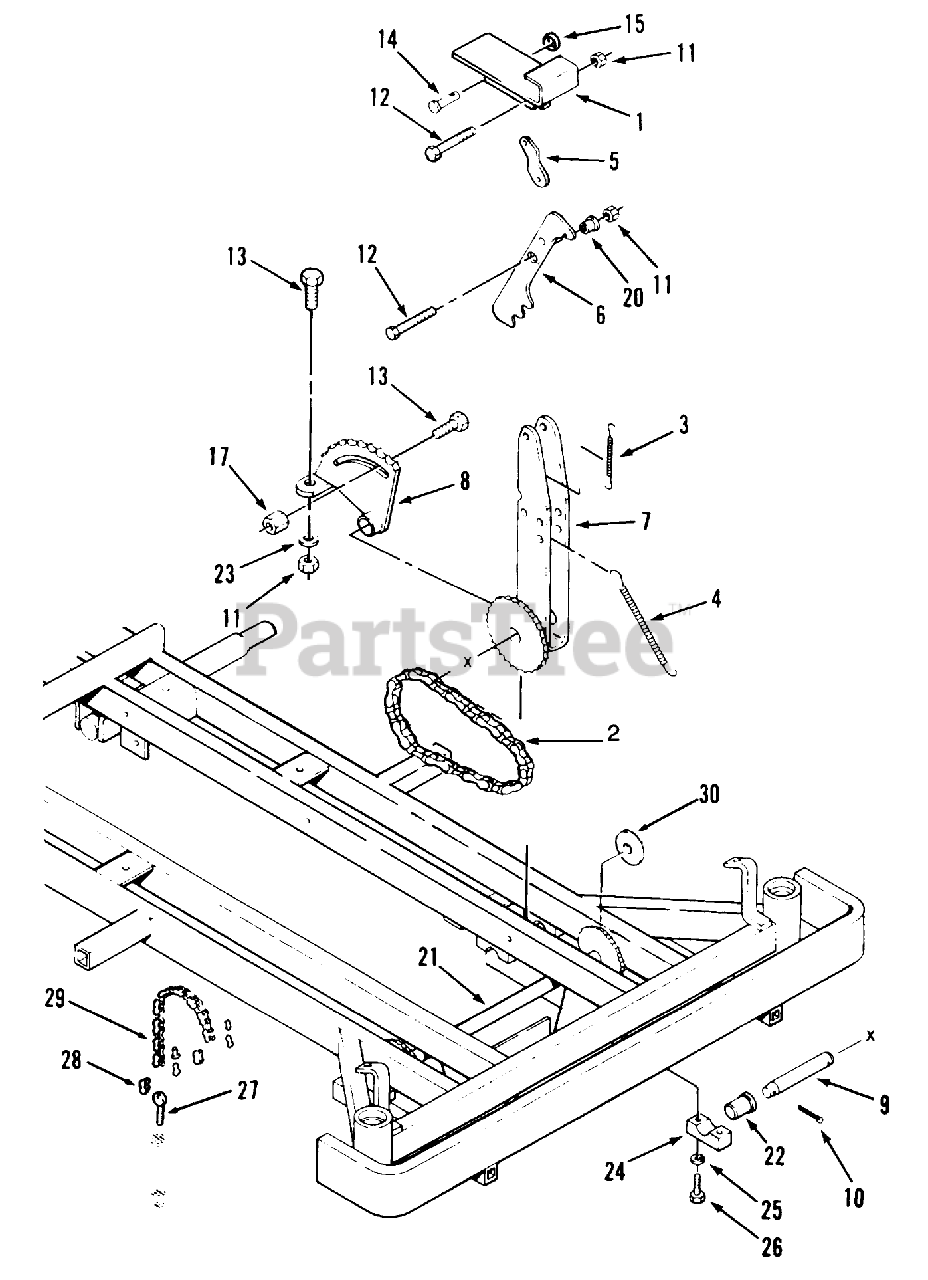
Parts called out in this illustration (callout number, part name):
2	CHAIN-FOOT PEDAL DR
3	SPG-NEUTRAL 20217-35
4	SPRING - EXTENSION
6	LIFT-ARM PWL *B
7	ASSY-LVR ARM 1022 *B
9	PIN-PEDAL
10	PIN-COTTER
11	NUT-LOCK, NI
12	SPIROL PIN H D
13	SCREW-HH
14	PIN-LOCK
15	E RING
17	HEX-STOP NUT N-140
20	BUSHING-PDL
22	BEARING-FLANGED
23	WASHER-PLAIN
25	WASHER-FLAT
26	SCREW-HH
27	EYE-BOLT 3/8-16X2.50
29	CHAIN-DECK LIFT
